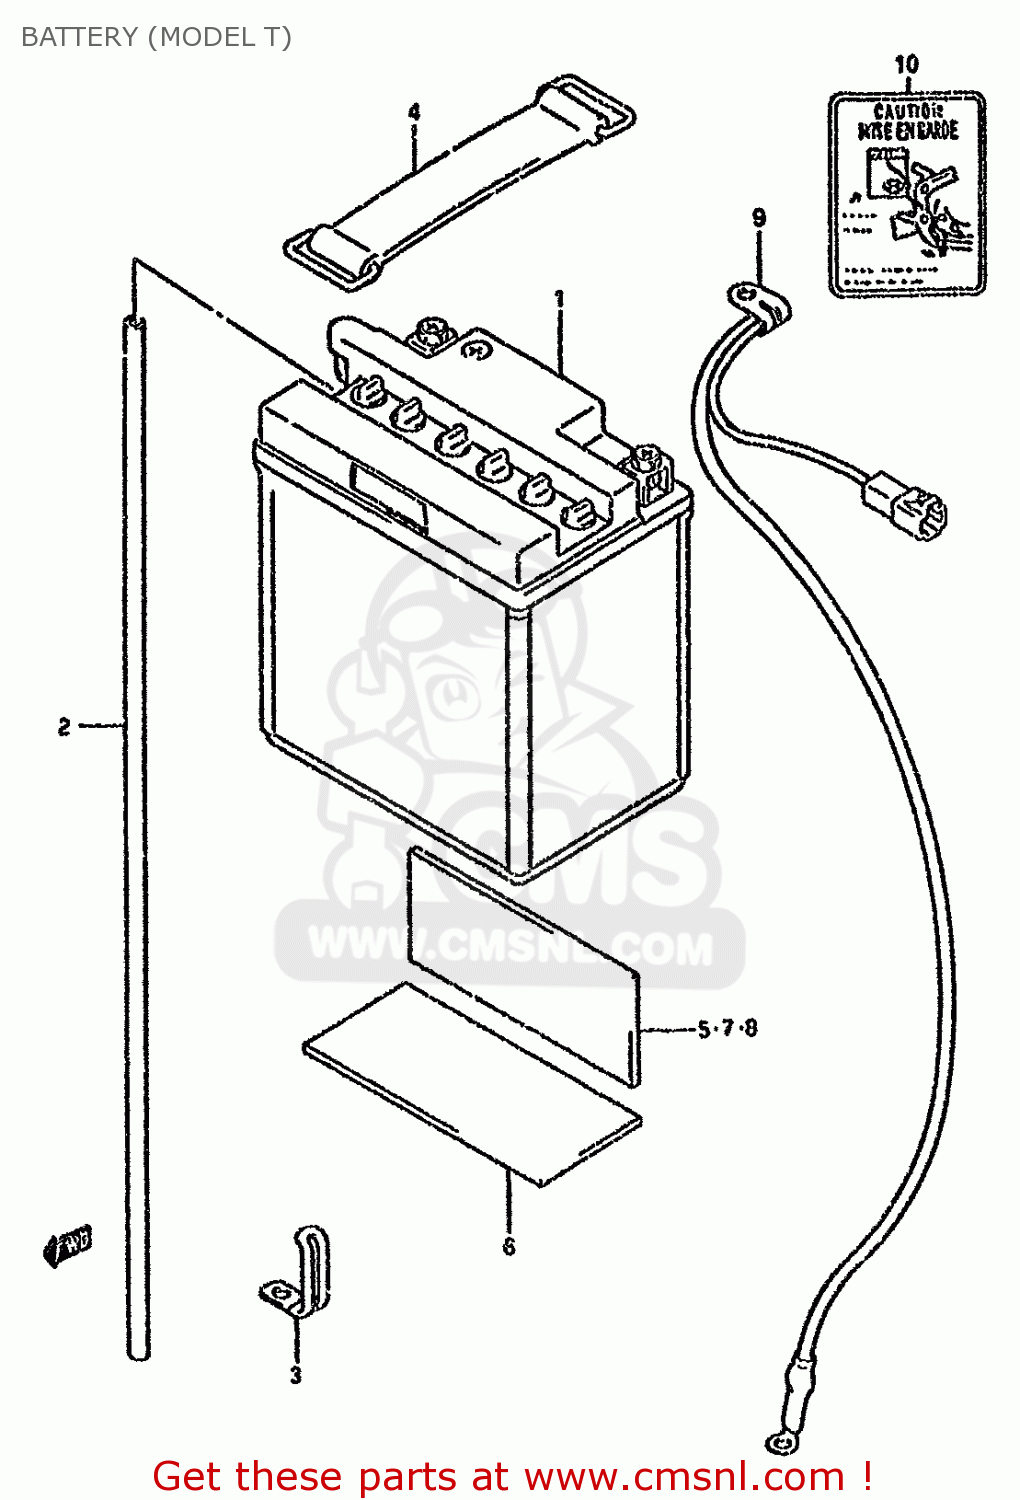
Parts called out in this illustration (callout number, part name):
1	BATTERY(YB10L-B2,12V11.6AH)
2	HOSE,BATTERY EXHAUST(L:780)
3	CLAMP(L:45)
4	BAND
5	PROTECTOR(170X95X3.0)
6	PROTECTOR(50X50X5)
7	PROTECTOR(170X95X3.0)
8	PROTECTOR(170X95X3.0)
9	WIRE,BATTERY MINUS LEAD
10	PLATE,BATTERY CAUTION
